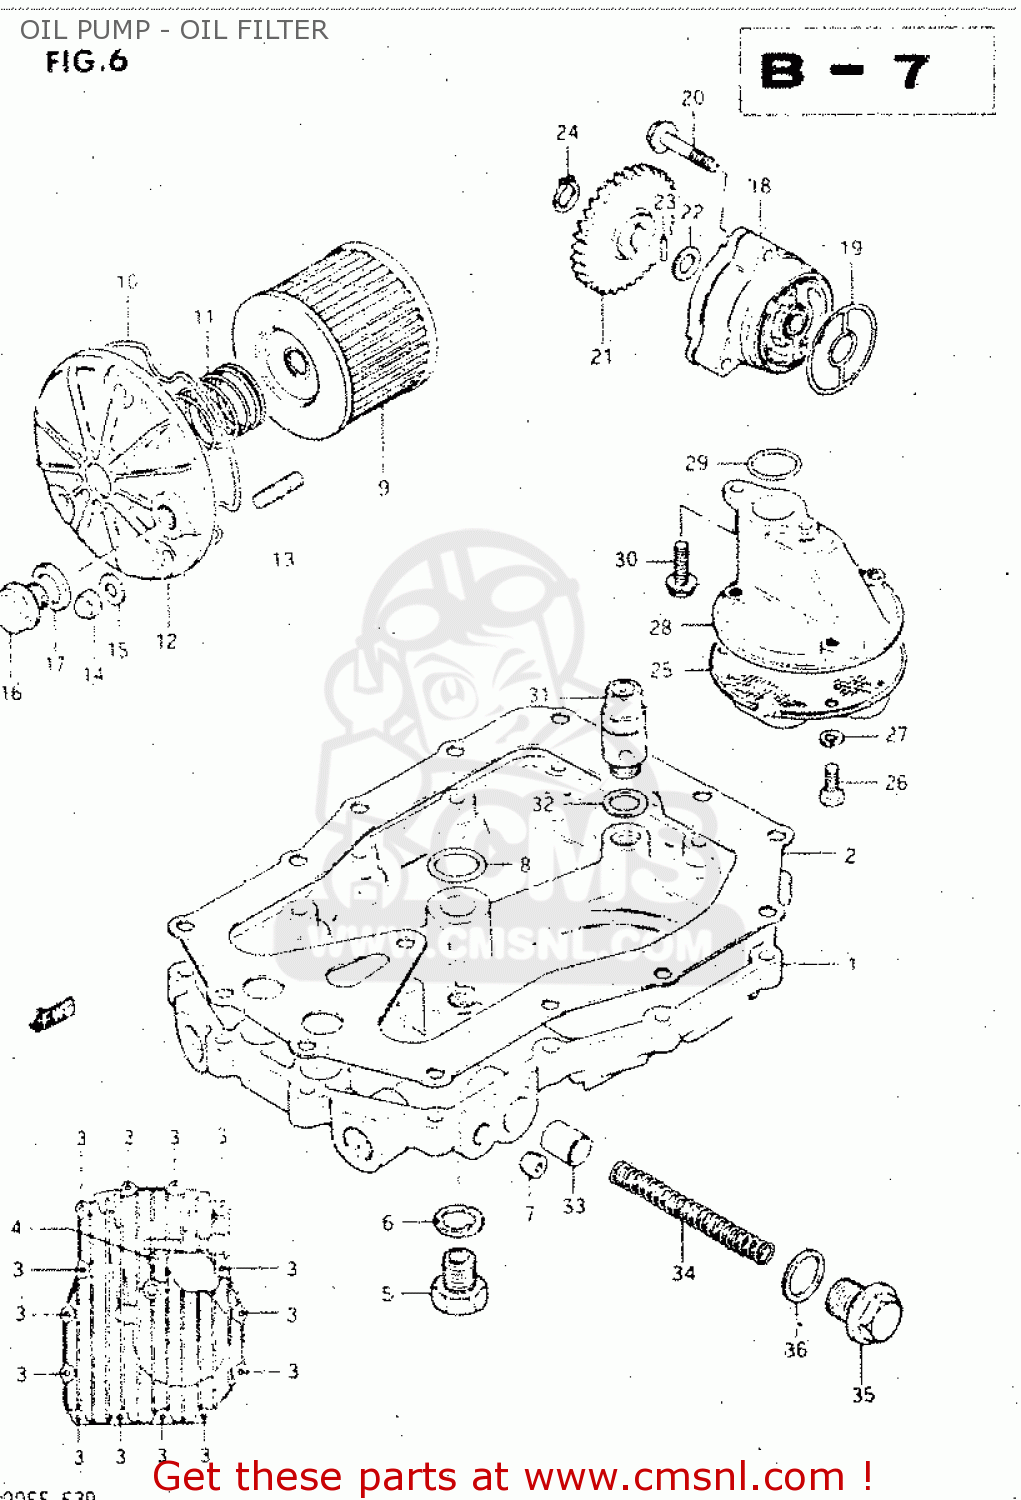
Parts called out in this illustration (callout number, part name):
1	PAN,OIL
2	GASKET,OIL PAN (MCA)
3	BOLT
4	BOLT 6X35
5	PLUG
6	GASKET(14X19.2X2) (NAS)
7	PLUG
8	O RING(D:3.2,ID:17.8)
9	FILTER ASSY,ENGINE OIL
10	O RING,OIL FILTER CHAMBER CAP
11	SPRING
12	CAP,OIL FILTER
13	STUD 6X20
14	NUT 6MM
15	WASHER
16	PLUG(14X12)
17	GASKET(14X19.2X2) (NAS)
18	PUMP ASSEMBLY,ENGINE OIL
19	O RING,OIL PUMP
20	BOLT(6X32)
21	GEAR,OIL PUMP DRIVEN
22	SHIM
23	PIN(4X15.8)
24	CIRCLIP
25	STRAINER,ENGINE OIL
26	BOLT
27	LOCK WASHER
28	PROTECTOR,OIL STRAINER
29	O RING(D:3.2,ID:17.8)
30	BOLT,REAR
31	REGULATOR ASSEMBLY,ENGINE
32	WASHER
33	PLUNGER,OIL CONTROLL
34	SPRING
35	PLUG
36	O RING(D:2.4,ID:16.8)
